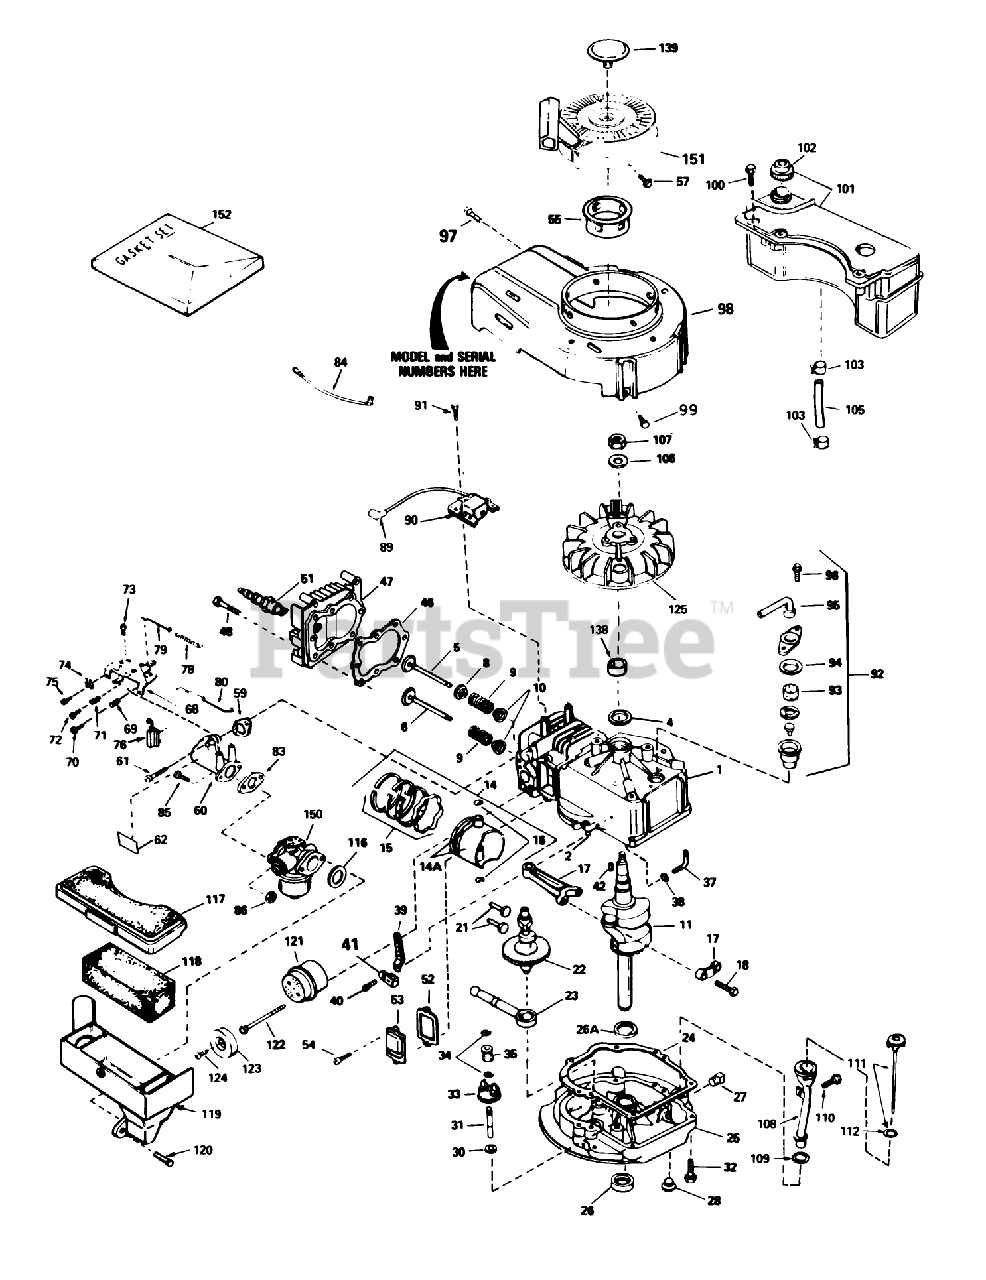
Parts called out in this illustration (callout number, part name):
1	Cylinder Assy. (Incl. #24)
2	Pin-Dowel
4	Seal-Oil
5	Valve, Intake (Std.) (Incl. Ref. #40)
5	Valve, Intake (1/32" oversize)(Incl. No. 40)
6	Valve, Exhaust (Std.)(Incl. No. 40)
6	Valve, Intake (1/32" oversize)(Incl. No. 40)
8	Seal Assy., Intake
9	Spring-Valve
10	Cap-Valve, Spring
11	Crankshaft
14	Piston, Pin Ring Assy. (Std.) (Incl. Ref. #13A, 14 15)
14	Piston, Pin Ring Assy. (.010 oversize) (Incl. Ref. #13A, 14 15)
14	Piston, Pin Ring Assy. (.020 oversize) (Incl. Ref. #13A, 14 15)
14A	Piston Pin Assy. (Incl . Ref. . #14) (Std.)
14A	Piston Pin Assy. (Incl. Ref. #14) (.010 Oversize)
14A	Piston Pin Assy. (.020 oversize) (Incl. Ref. #14)
15	Ring Set (Std.)
15	Ring Set (.020" OS)
15	Ring Set (.010" OS)
16	Ring-Retaining, Piston Pin
17	Rod Assy., Connecting (Incl. Ref. #17)
18	Bolt-Rod, Connecting
21	Lifter-Valve
22	Camshaft(Mech.Comp. Release)
23	Oil Pump ASM
24	Gasket
25	Flange-Mounting (Incl. Ref. #26, 27 39)
26	Seal-Oil
26A	Washer-Thrust
27	Plug-Pipe
28	Plug Oil Drain
30	Washer-Flat
31	Shaft-Governor
32	Screw (1/4-20 x 1-1/4)
33	Governor Gear ASM
34	Ring-Retaining
35	Spool-Governor
37	Rod, Governor (Incl. No. 36)
38	Washer-Flat
39	Governor Lever
40	Screw
41	Clamp-Lever, Governor
42	Key-Flywheel
46	63573 GIL 42 SNWTHW
47	Head-Cylinder
48	Screw (5/16-18x1-1/2)
51	Spark Plug-Resistor (R J19 L M)
52	Gasket-Breather
53	Cover-Valve
54	Screw
55	Hub-Starter
57	Screw, Hex Hd.
59	Gasket-Intake
60	Pipe-Intake (Incl. Ref. #59)
61	Screw (1/4-20 x 1)
62	Decal-Primer
68	Control Assy.-Remote Speed (Incl. Ref. #69 thru 72 76)
69	61709/GIL1515A/95-5
70	Screw
71	Spring-Compression
72	Screw
73	Screw (10-24 x 9/16)
74	Conduit
75	Screw (10-32 x 3/8)
76	Terminal
78	Spring Governor
79	2035A67 ADD.ASSEMBL
80	Link-Throttle
83	Gasket
84	Wire-Ground
86	Nut and Lock Washer (1/4-28)
89	Cover-Spark Plug
90	Solid State
91	Screw
92	Breather Assy. (Incl. Ref. #46 thru 51)
93	Element-Breather
94	*33735 Gasket-Breather
95	Tube, Breaker
96	Screw (10-24 x 9/16)
97	Screw (10-24 x 9/16)
98	Housing-Blower
99	Screw (1/4-20 x 1/2)
100	Screw (10-32 x 35/64)
101	Tank Assembly-Fuel (Incl. Ref. #102)
102	Cap-Fuel
103	Clamp-Line, Fuel
105	Line-Fuel
106	Washer-Belleville
107	Nut-Flywheel
108	Tube-Oil Fill
109	Gasket
110	Screw (10-32 x 1/2)
111	Dipstick-Oil (Incl. Ref. #112)
112	O-Ring
116	Gasket-Cleaner, Air
117	Cover Air Cleaner
118	Filter-Air Cleaner
119	Body Air cleaner
120	Screw
121	B Muffler (Incl. Ref. #122)
122	Screw
123	Cover-Muffler
124	Screw (8-32 x 3/8)
125	Flywheel
138	Spacer
139	Plug Starter
150	Carburetor (Incl. Ref. #83)
151	Starter-Rewind
152	Gasket Set
